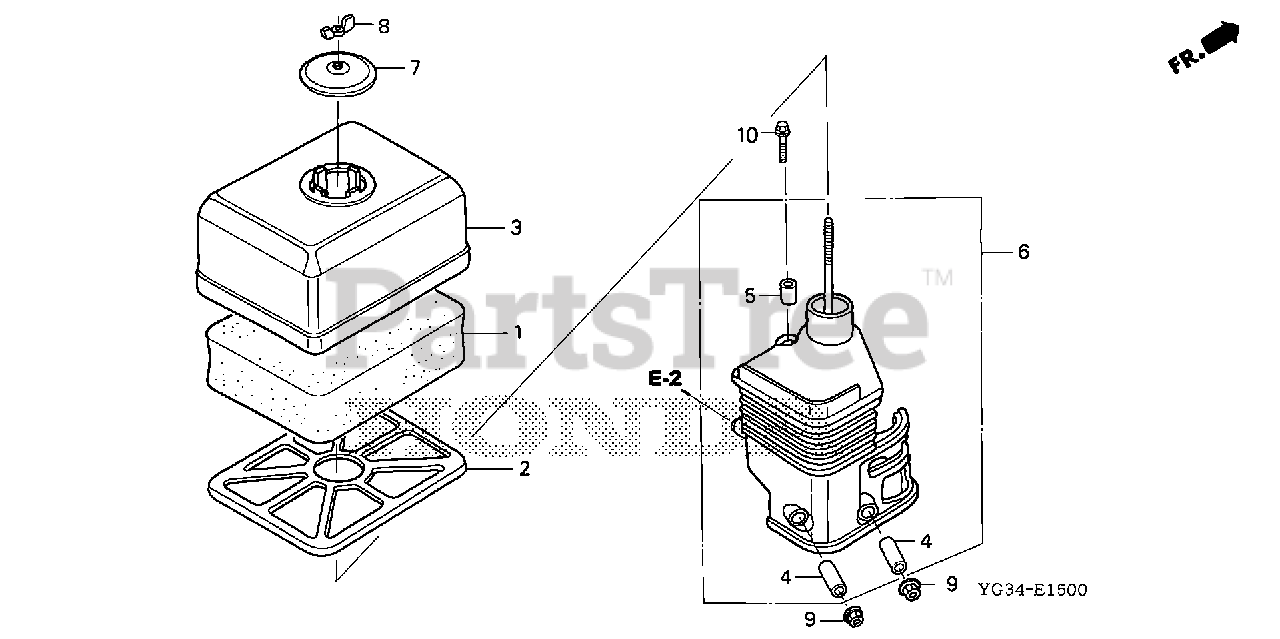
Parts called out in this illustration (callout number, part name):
1	ELEMENT, AIR CLEANER (SEMI-DRY)
2	GRID, AIR CLEANER (SEMI-DRY)
3	COVER, AIR CLEANER (SEMI-DRY)
4	COLLAR, AIR CLEANER
5	COLLAR B, AIR CLEANER
6	ELBOW, AIR CLEANER
7	CAP, CLEANER
8	NUT, TOOL BOX SETTING
9	NUT, FLANGE (6MM)
10	BOLT, FLANGE (6X20)
